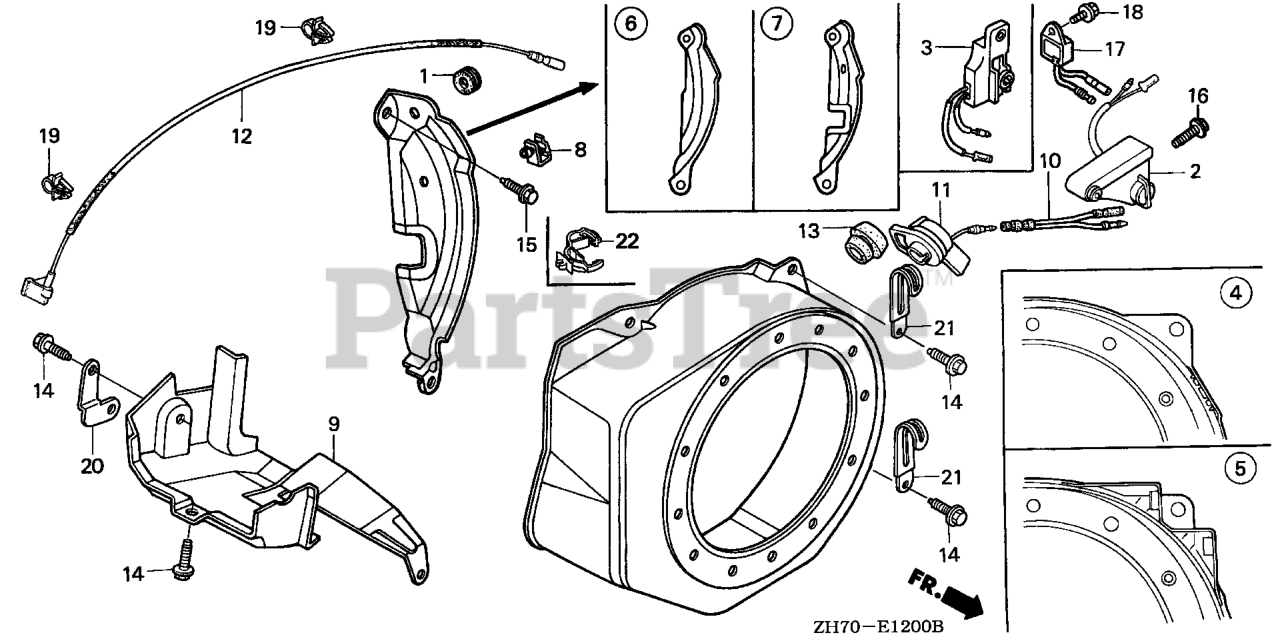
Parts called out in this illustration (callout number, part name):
1	GROMMET, ADJUSTING COVER
2	ALERT UNIT, OIL
4	COVER, FAN *NH1* (BLACK)
4	COVER, FAN *R280* (POWER RED)
5	COVER, FAN *R8* (OIL ALERT) (BRIGHT RED)
6	PLATE, SIDE (OIL ALERT)
8	CLAMP, CORD
10	SUB-HARNESS
11	SWITCH ASSY., ENGINE STOP Use from Engine SN 2092216 to 2359126.
11	SWITCH ASSY., ENGINE STOP
12	WIRE, STOP SWITCH (370MM)
14	BOLT, FLANGE (6X12) (CT200)
15	BOLT, FLANGE (6X20) (CT200)
16	BOLT, FLANGE (6X8)
17	ALERT UNIT, OIL
18	BOLT, FLANGE (6X8)
22	CLIP, HARNESS
